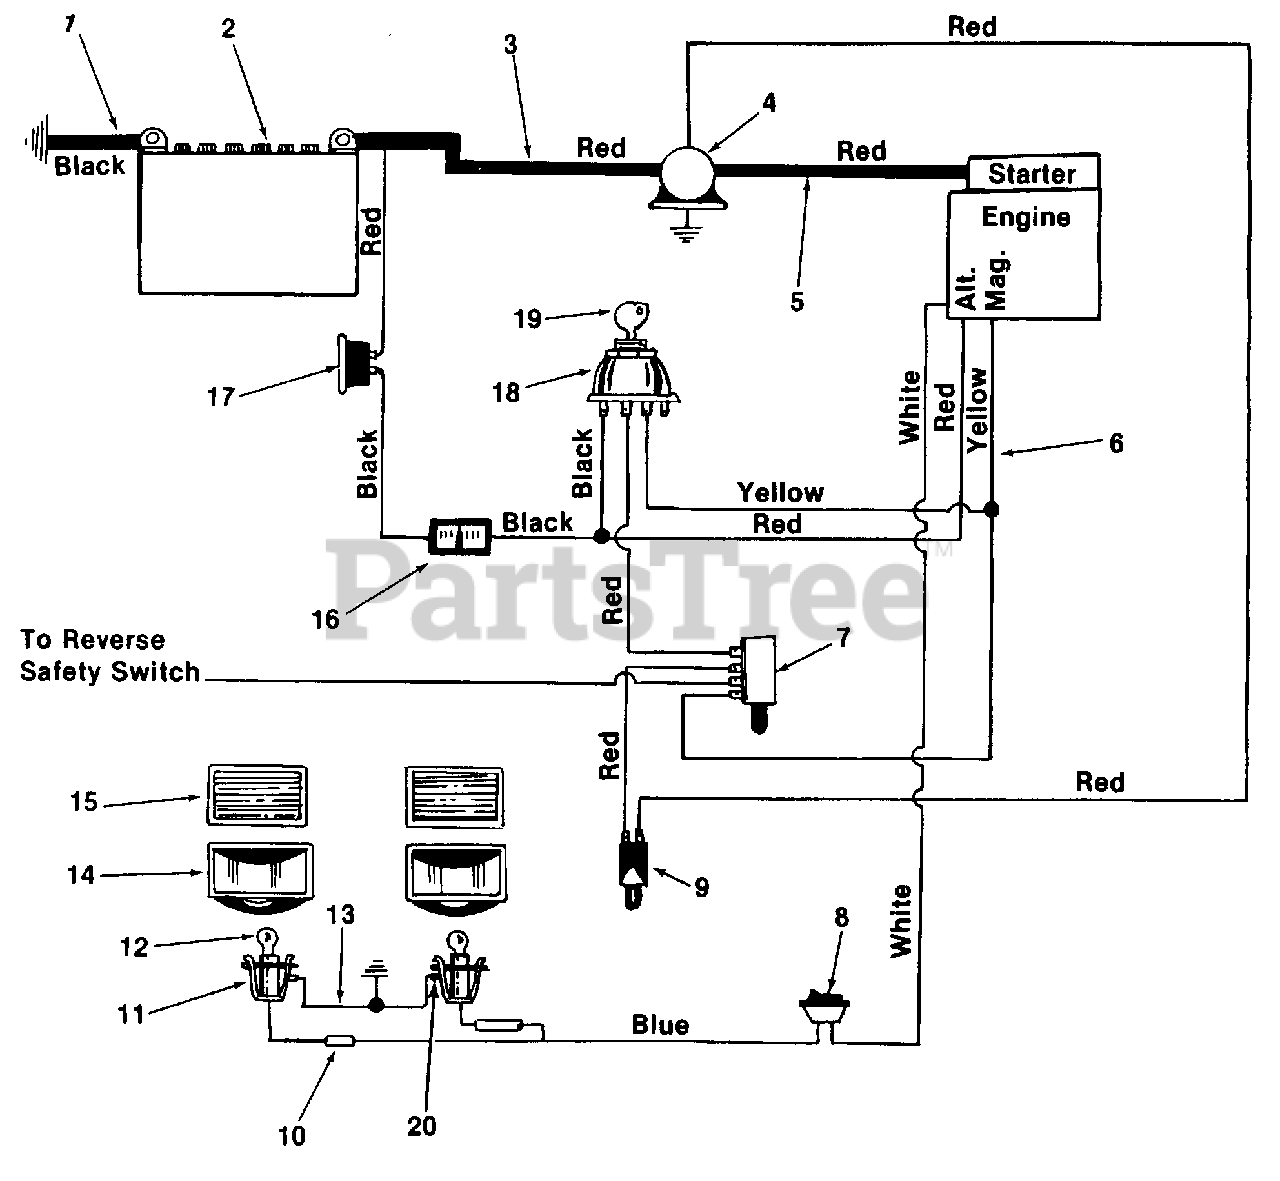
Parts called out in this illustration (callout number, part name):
1	Electric Wire
2	1 2V-Battery
3	Electric Wire
4	Solenoid
5	Electric Wire
6	Wire Harness
7	Safety Switch
8	Light Switch
9	Safety Switch
10	Tab Receptacle
11	Socket
12	Lamp
13	Ground Wire
14	Head Light Housing
15	Lens
16	Ammeter
17	Circuit Breaker
18	Ignition Switch
19	Ignition Key
20	Push on Ground Clip
